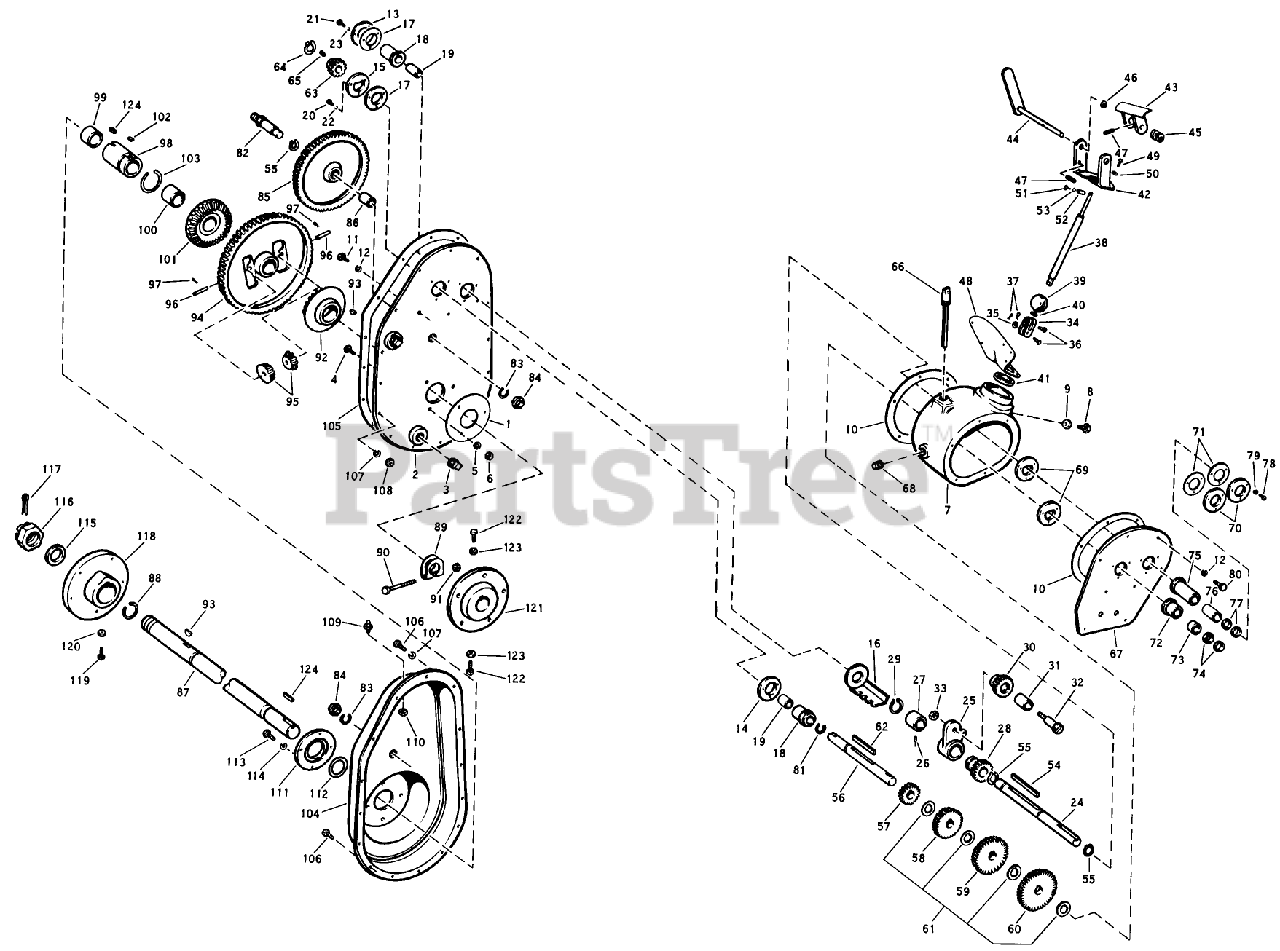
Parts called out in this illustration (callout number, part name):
1	SRV BULLT 437B
2	Back Plate Assembly
3	Pipe Plug 1/2-14
6	Hex Jam Nut
8	Capscrew 3/8-16 x 1 Lg.
11	Hex Capscrew 1/4-20 x 1/2 Lg.
12	Lift Bar
14	Bearing Retainer
15	Bearing Retainer
16	Speed Selector Assembly
18	Bearing Tube Assembly
20	Spring-Auger Disengage
23	Lockwasher #10
24	Input Shaft
25	Rocker Arm Assembly
27	Bushing
28	Transmission Slide Gear
30	Rocker Arm Pinion Assembly
32	Rocker Arm Pinion Shaft
33	Lock Nut 1/2-20 NF
34	Shifter Clevis
36	Clevis Pin
37	Cotter Pin 3/32 x 1/2 Lg.
38	Gear Shift Lever
39	Shifter Ball
42	Support Assembly
43	Lock In Assembly
44	Lock In Lever Assembly
47	Roll Pin
49	Machine Screw #10-32 x 3/4 Lg.
50	Lockwasher #10
51	Machine Screw #10-32 x 1-1/2 Lg.
53	Lockwasher #10
59	Low Gear (26 teeth)
62	SPRING-EXTENSION
64	Retaining Ring
66	Dip Stick Assembly
68	Pipe Plug 3/8-18
72	Bearing Tube Assembly, Short
73	Bushing
75	Bearing Tube Assembly, Lg.
79	Lockwasher #10
80	Hex Head Capscrew 1/4-20 x 3/4 Lg.
82	Intermediate Shaft
83	Lockwasher 5/8
84	Hex Jam Nut 3/8-18
85	Intermediate Gear Assembly
88	Retaining Ring
89	SHIFT KNOB
90	Capscrew 3/8-24 x 2-1/2 Lg.
91	Hex Nut
92	SHAFT-PTO
94	Differential Spur Gear (66 teeth)
96	Differential Pinion Shaft
97	Cotter Pin 1/8 x 1-1/2 Lg.
98	Differential Tube Assembly
99	Bushing
104	Gear Case Cover Assembly
105	Gear Case Gasket
106	Hex Capscrew 1/4-20 x 1/2 Lg.
107	Lift Bar
108	Hex Nut
109	Grease Fitting
110	Hex Jam Nut
113	Hex Capscrew 1/4-20 x 1/2 Lg.
114	Lift Bar
116	Slotted Hex Nut 1-1/4 x 12
117	Cotter Pin 1/4 x 2 Lg.
118	HEADLAMP
119	Set Screw 3/8-16 x 1-1/4 Lg.
122	Set Screw 3/8-16 x 1-1/4 Lg.
